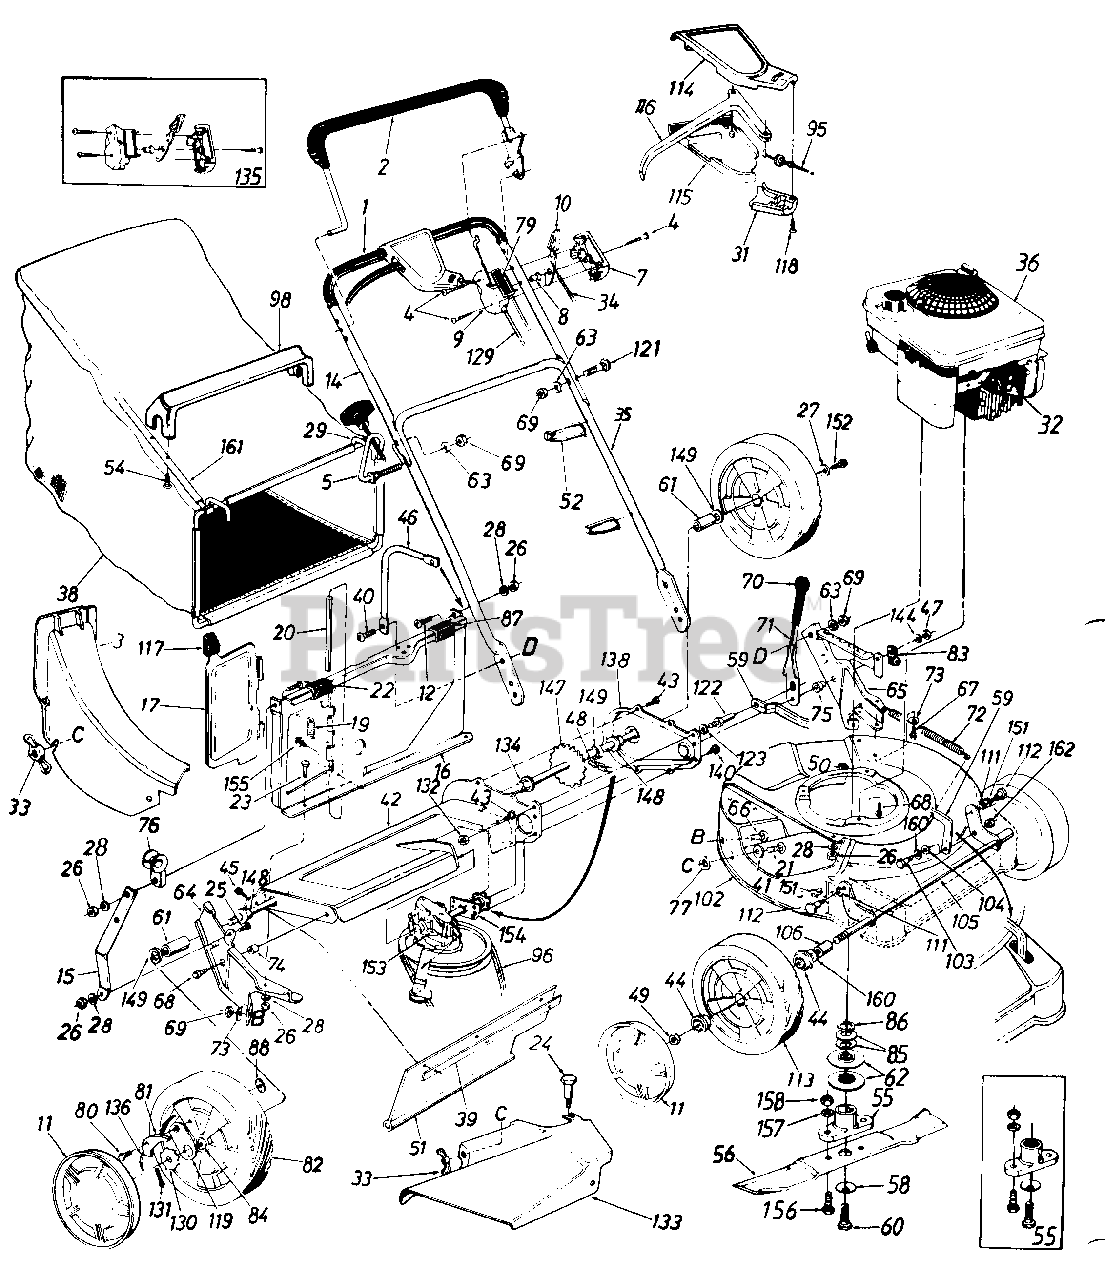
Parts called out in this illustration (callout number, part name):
1	Foam Grip
2	Control Handle Ass'y.-L.H.
3	Rear Discharge Chute Ass'y.
4	Truss Mach. Scr. #12 x 1.50" Lg.
5	Rope Guide Bolt
7	Control Panel Half
8	Control Disc Pin
9	Clutch Panel Half
10	Throttle Control Lever
11	Hub Cap
12	Truss Mach. Scr. 1/4-20 x .62" Lg.
14	Upper Handle-Painted
19	Torsion Spring
20	Pivot Pin
21	Carriage Bolt 1/4-20 x .62"
22	Truss Mach. Scr. 1/4-20 x 3/4" Lg
23	Hex Bolt 1/4-20 x .50" Lg.
24	Shoulder Bolt .312 Dia. x .18 Lg.-Special
25	Hex Bolt 1/4-20 x .62" Lg.
26	Hex Nut 1/4-20 Thd.
27	Bell-Wash. 1/4" I.D.
28	L-Wash. 1/4" I.D.
31	S.P. Control Cover
32	Spark Plug Insulator
33	Wing Nut w/Washer
34	Throttle Control Wire 61"
35	Lower Handle-Painted
36	Engine
38	Grass Bag
39	Retaining Strip
40	Truss Mach. Scr. 5/16-18 x .75" Lg.
41	Fl-Wash. .344" I.D. x .62"
44	Flange Ball Bearing 1/2" I.D.
45	Hex AB-Tap Scr. 1/4 x .62"
46	Catcher Panel Support Arm
47	Hex Patch L-Nut 3/8-24 Thd.
48	#48 Chain .500" Pitch x 30 Links
49	Hex L-Nut 1/2-20 Thd.
51	Rear Flap 3.75" x 17.30" Lg.
52	Cable Tie
54	Hex AB Scr. #12 x 1.25" Lg.
55	Blade Adapter Kit
56	21" Blade
58	Bell-Wash. .46" I.D. x 1.13" O.D.
59	Height Adj. Connecting Arm
60	Hex Bolt 7/16-20 x 1.5" Lg. (Grade 5)
61	Spacer. 513" I.D. x .703" O.D. x .69" Lg.
62	Serrated Pulley Half
63	L-Wash. 5/16" I.D.
64	R.H. Handle Wheel Brkt. Ass'y.
65	L.H. Handle Wheel Brkt. Ass'y.
66	Carriage Bolt 5/16-18 x .62"
67	Hex Wash. Hd. B-Tap Scr. 5/16-18
68	Hex Wash. Hd. TT-Tap Scr. 3/8-16
69	Hex Nut 5/16-18 Thd.
71	Height Adj. Lever
72	Extension Spring .75" O.D. x8" Lg.
73	Bell-Wash. 5/16" I.D.
74	Spacer
75	Shld. Spacer .500" Dia.
76	Rope Guide
77	Bolt Retainer 1/4 x .50" O.D.
79	Control Label
80	Shld. Scr. .342" Dia. x .268
81	Pawl
82	Wheel Ass'y. Comp.
83	Clamp
84	Bearing 1/2" I.D.
85	Bell-Washer 1.01" I.D.
86	Crankshaft Spacer
87	Panel Clip
88	Flat Weld Nut 1/4-20 Thd.
95	S.P. Cable
96	"V"-Belt
98	Bag Handle
102	21" Deck Ass'y.
103	Shld. Bolt .5" Dia. x .295
104	Bell-Wash. .515" I.D. x 1.0" O.D.
105	Front Axle Ass'y.
106	Sleeve .526" I.D. x .690" O.D. x .880" Lg.
111	Intern. L-Wash. 3/8 I.D.
112	Shld. Bolt .575" Dia. x .42
113	Wheel Ass'y. Comp.
114	Self-Propelled Control Cover
115	Self-Propelled Control Cover
116	Control Lever
117	Door Grip
118	Fl-"C"-Sunk Hd. Tap Scr. #10 x .75" Lg.
119	Pawl Plate
121	Curved Carr. Bolt 5/16-18 x 1.38" Lg.
122	Shld. Pin 3/8-24 x 1.43" Lg.
123	L-Wash. 3/8" I.D.
129	Control Cable 43" Lg.
130	Ratchet Wheel 1.62" O.D.
131	Cotter Pin 1/8" Dia. x 1.00" Lg.
132	Hex Jam Nut 3/8-24 Thd.
133	Side Chute Deflector Ass'y.
134	Hex Flange Bearing
135	Kit-Control Housing Comp.
136	Spring-Nylon
144	Fl-Wash. .385" I.D. x .87"
147	Rear Shaft Ass'y. 21.94" Lg.
148	Hex Flange Bearing .506" I.D. Plastic
149	Fl-Wash. .531" I.D. x .930"
151	Flanged Nyliner Brg.
152	Hex Bolt 1/4-20 x .62" Lg. (Grade 5)
153	Transmission Comp.
155	Hex B-Tap Scr. #10 x .38
156	Hex Scr. 3/8-24 x 1.0" Lg.
157	L-Wash. 3/8" I.D.
158	Hex Nut 3/8-24 Thd.
160	Fl-Wash. .51" I.D. x .75" O.D.
162	Hex Jam Nut 3/8-16 Thd.
17055B-0637	AXLE ASSY-CHAIN - POWDER BLACK (0637)
17055B-0638	AXLE ASSY-CHAIN - MTD/TROY-BILT RED (0638)
17055B-0665	AXLE ASSY-CHAIN - YARDMAN GREEN (0665)
